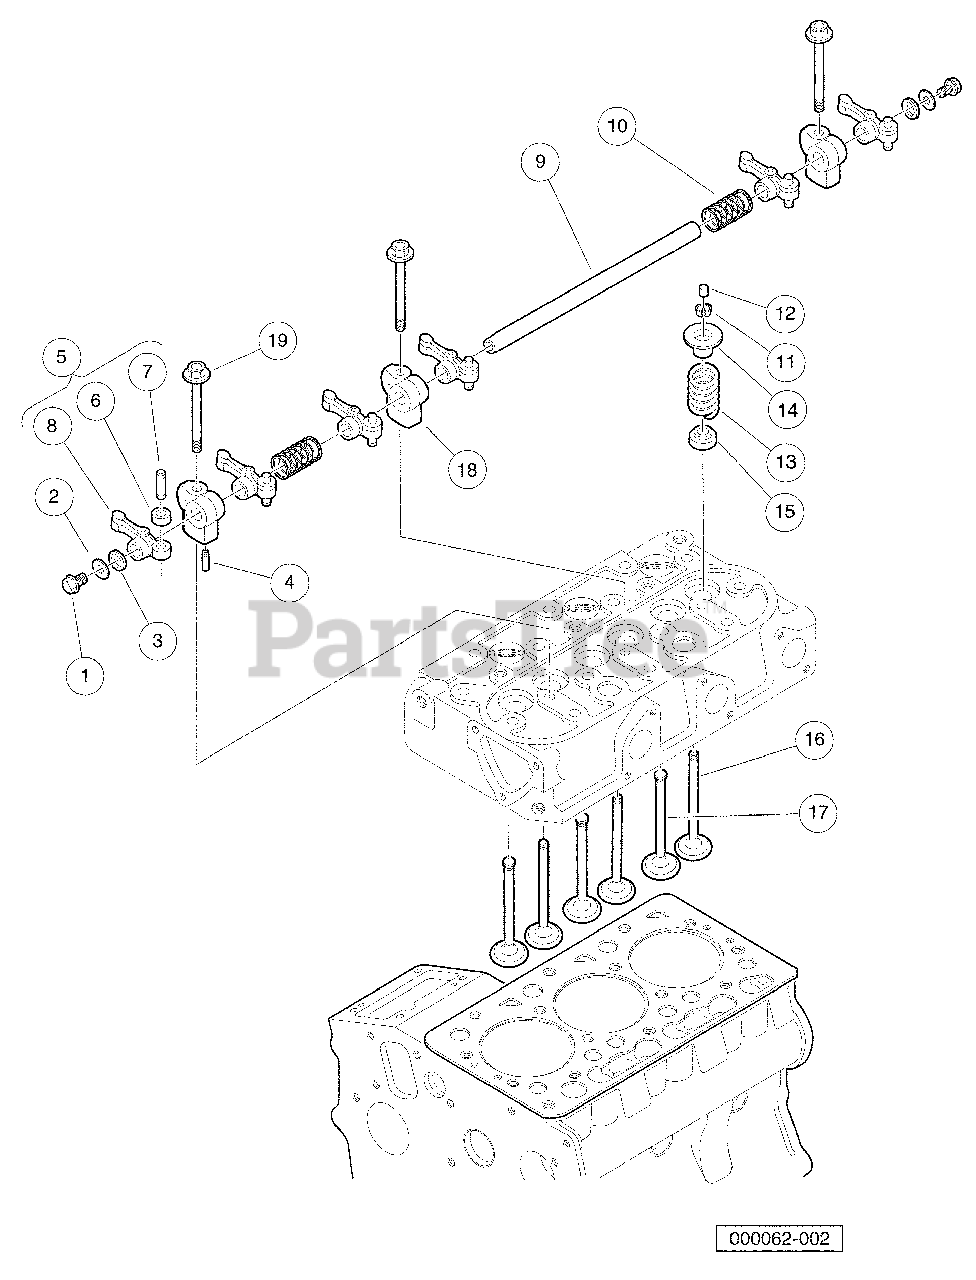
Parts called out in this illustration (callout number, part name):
1	Bolt, M6 X 1 X 8
2	Washer, D722, Plain, Rocker
3	Washer, Rocker Arm
4	Pin, Spring, D722, Rocker
5	Assy Rocker Arm
7	Screw-Adjusting
8	Arm, Rocker
9	Shaft, Rocker Arm
10	Spring, Rocker Arm
11	Collet, Valve Spring, Set.
12	Cap, Valve, D722
13	Spring, Valve..
14	Retainer, Spring.
15	Seal, Valve Stem.
16	Valve, Exhaust
17	Valve, Inlet.
18	Bracket, Rocker Arm, D722 Closed-Breather
19	Bolt, Rocker Arm
